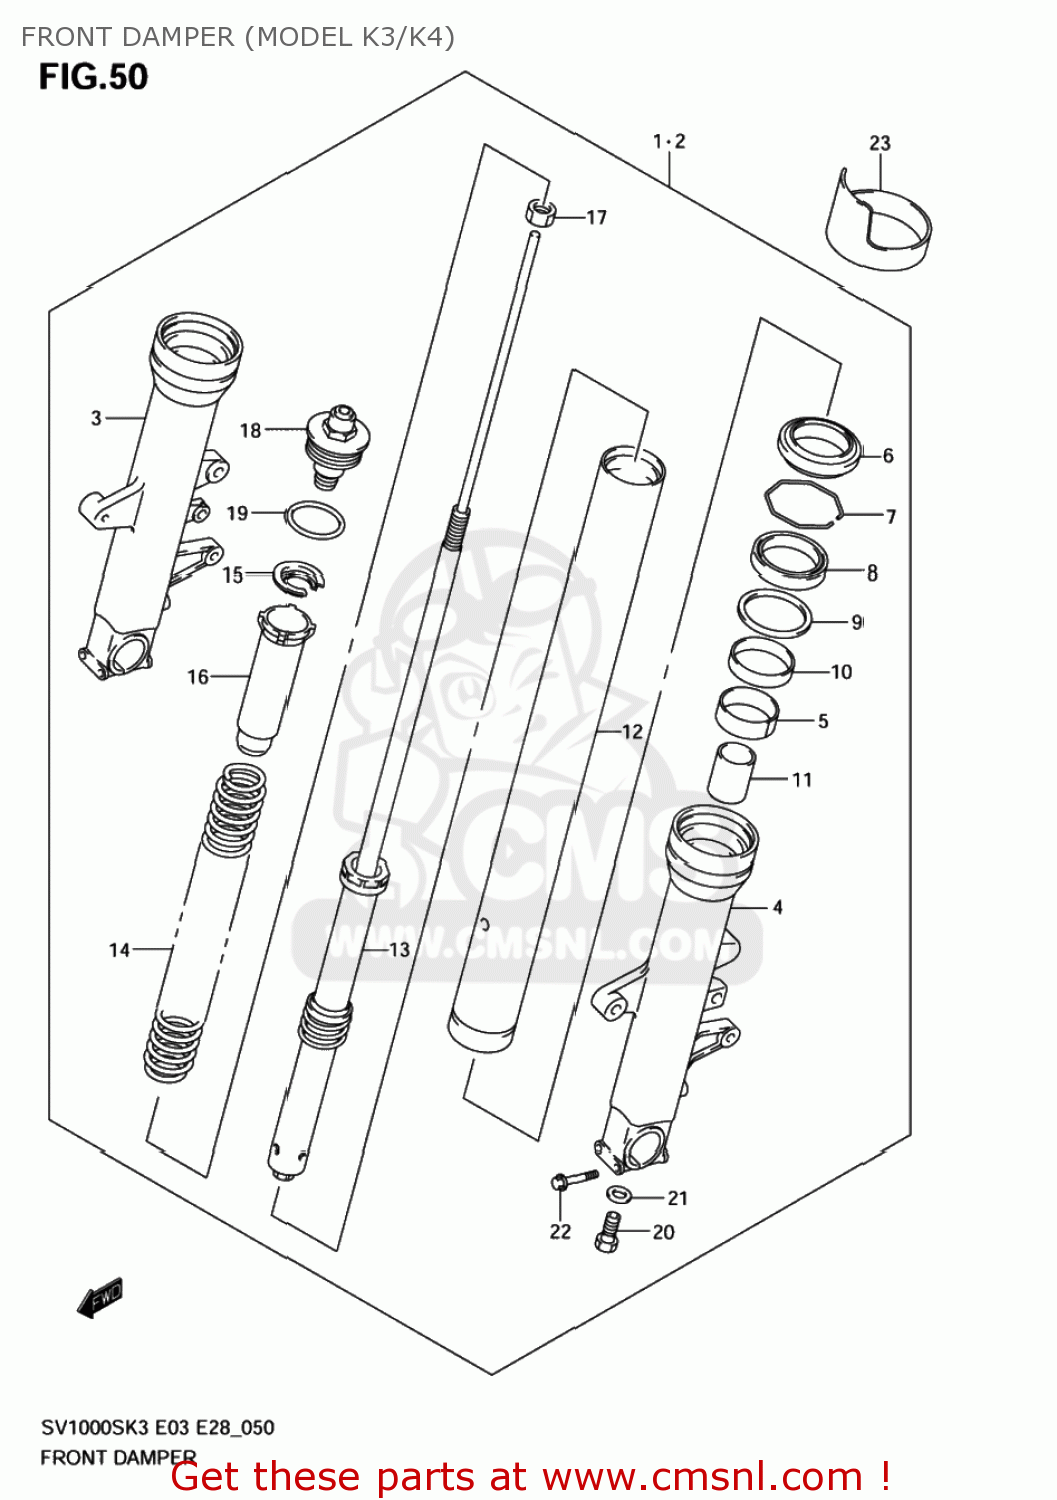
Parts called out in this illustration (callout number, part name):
1	DAMPER ASSY,FR FORK,R
2	DAMPER ASSY,FR FORK,L
3	TUBE,OUTER,R
4	TUBE,OUTER,L
5	BUSH,SLIDE
6	SEAL,DUST
7	RING,STOPPER
8	SEAL,OIL
9	WASHER
10	BUSH,GUIDE
11	PIECE,OIL LOCK
12	TUBE,INNER
13	CYLINDER
14	SPRING,FR
15	GUIDE,SPRING
16	SPACER
17	NUT
18	CAP,FORK
19	O RING
20	BOLT
21	GASKET (NAS)
22	BOLT
23	PROTECTOR
